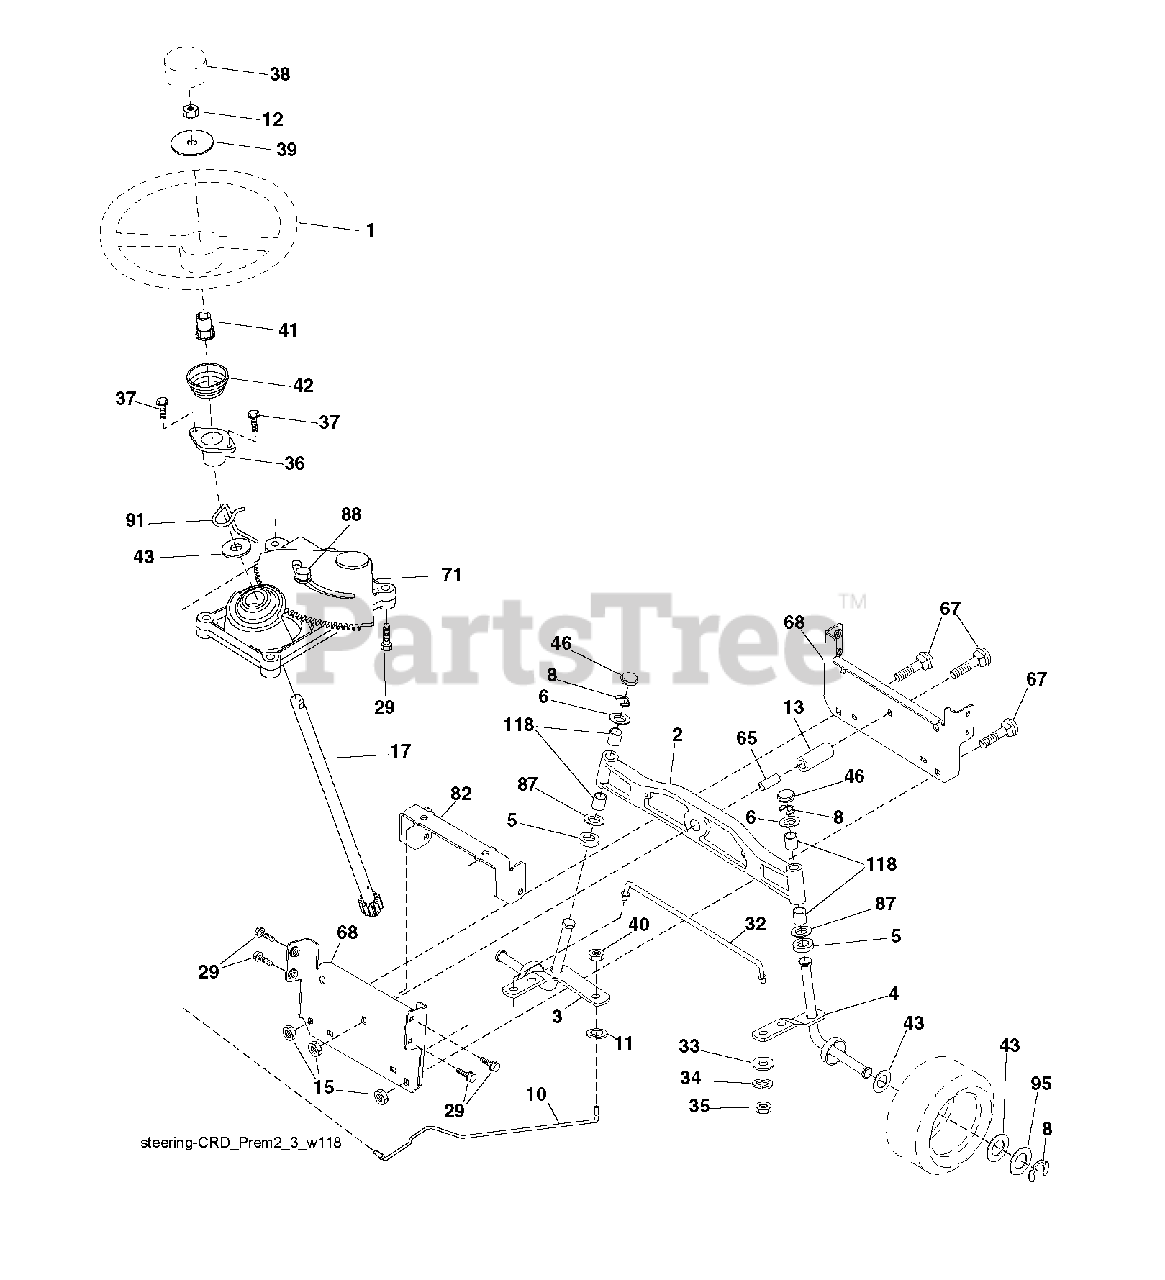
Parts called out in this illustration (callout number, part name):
1	WHEEL.STEERING.STDSRR.BLK/OV
2	AXLE.ASM.LT.CAST.LGHTWGHT
3	SPINDLE.ASM.LH.15"TIRES
4	SPINDLE.ASM.RH.15"TIRES
8	RING CLIP
10	DRAGLINK.15".TIRES.2001
11	WASHER, LOCK 3/8
12	NUT.HEX.1/2-20
13	TUBE, PIVOT AXLE
15	NUT
17	SHAFT ASM STRG
29	SCREW, 3/8-16X3/4
33	WASHER M
34	LOCKWASHER
35	NUT, CROWNLOCK
36	BUSHING, STRG. BLK
38	CAP.WHL.STRNG.STDSRRD.SRS.BLK
39	WASHER 9/16"ID, 2 3/8"OD
40	NUT CROWNLOCK 3/8-24
41	ADAPTER, WHEEL STNG..
42	BOOT.STEERING.
46	CAP.SPINDLE
65	SPACER.BRACE.AXLE
67	BOLT CARRIAGE
68	BRACE.AXLE.15"TIRES
71	STEERING ASM
82	BRACKET.SUSP.CHASSIS.FRONT.15
87	WASHER, FLAT .781 X 1 1/2"
88	BOLT, SHOULDER 7/16-20
91	CLIP.STEERING
95	WASHER.HARDENED
118	BUSHING, AXLE CAST
